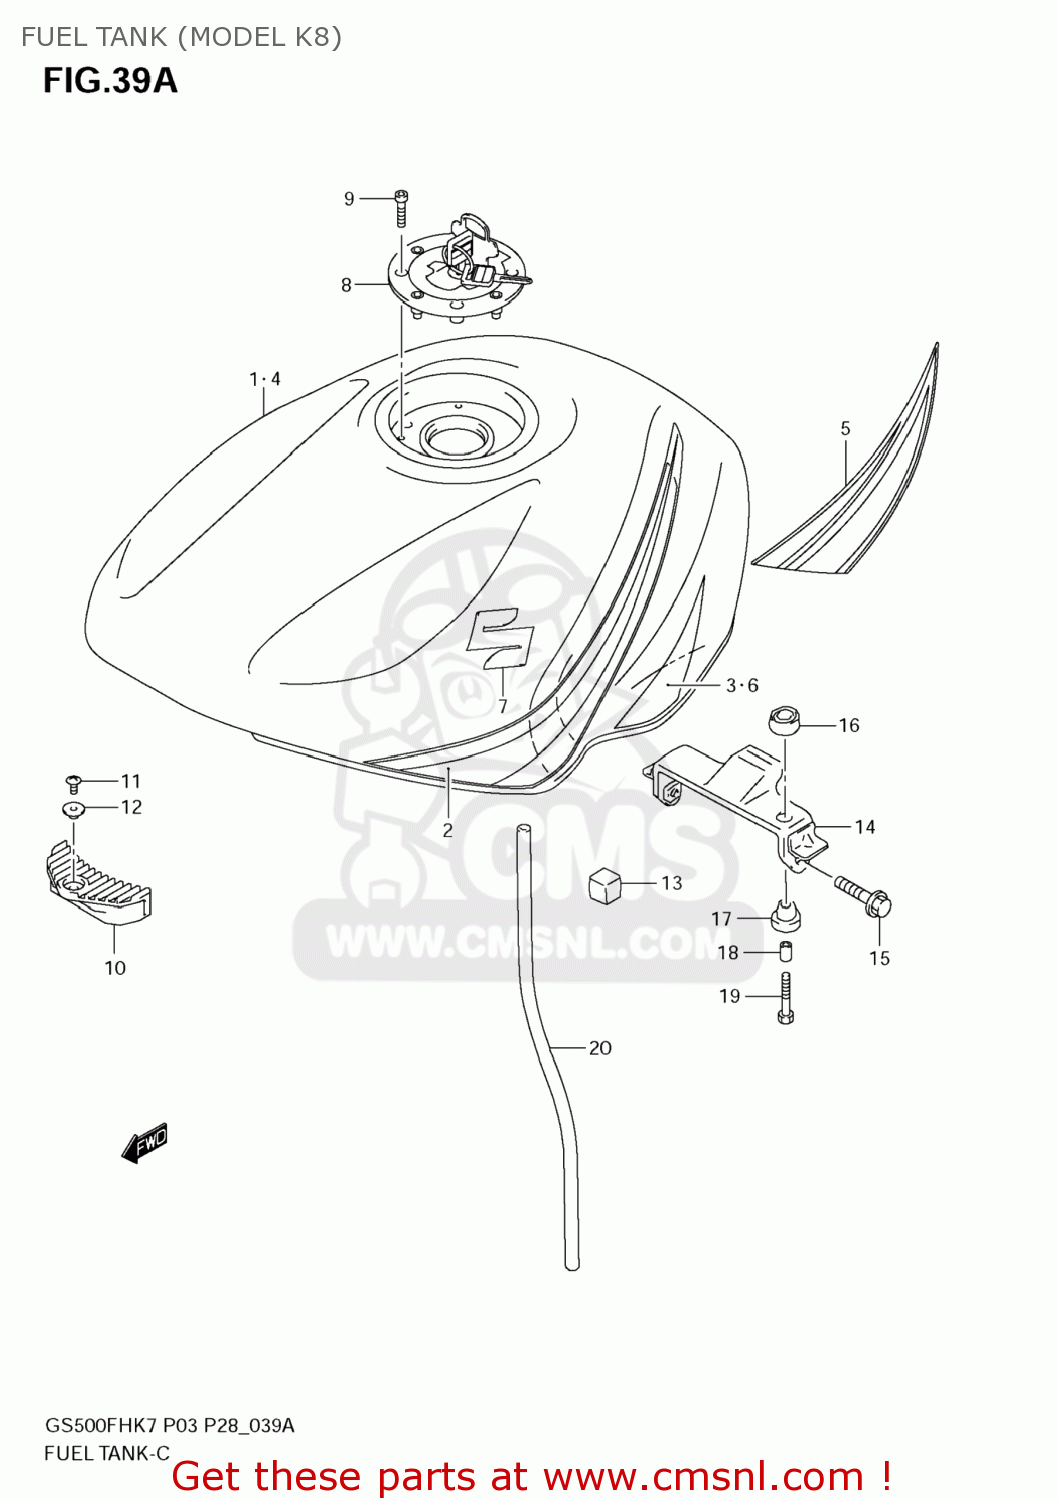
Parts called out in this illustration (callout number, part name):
1	TANK ASSY,FUEL(GRAY)
2	TAPE SET,FUEL TANK
3	TAPE SET,FUEL TANK LWR
4	TANK ASSY,FUEL(BLUE)
5	TAPE SET,FUEL TANK
6	TAPE SET,FUEL TANK LWR
7	EMBLEM,S
8	CAP SET,FUEL TANK
9	BOLT(5X20)
10	CUSHION,FUEL TANK FR
11	SCREW, THROTTLE CABLE
12	WASHER
13	CUSHION,FUEL TANK SIDE
14	BRACKET, REAR
15	BOLT
16	CUSHION
17	CUSHION
18	SPACER(6.5X9X18)
19	BOLT(6X30)
20	HOSE, DRAIN
